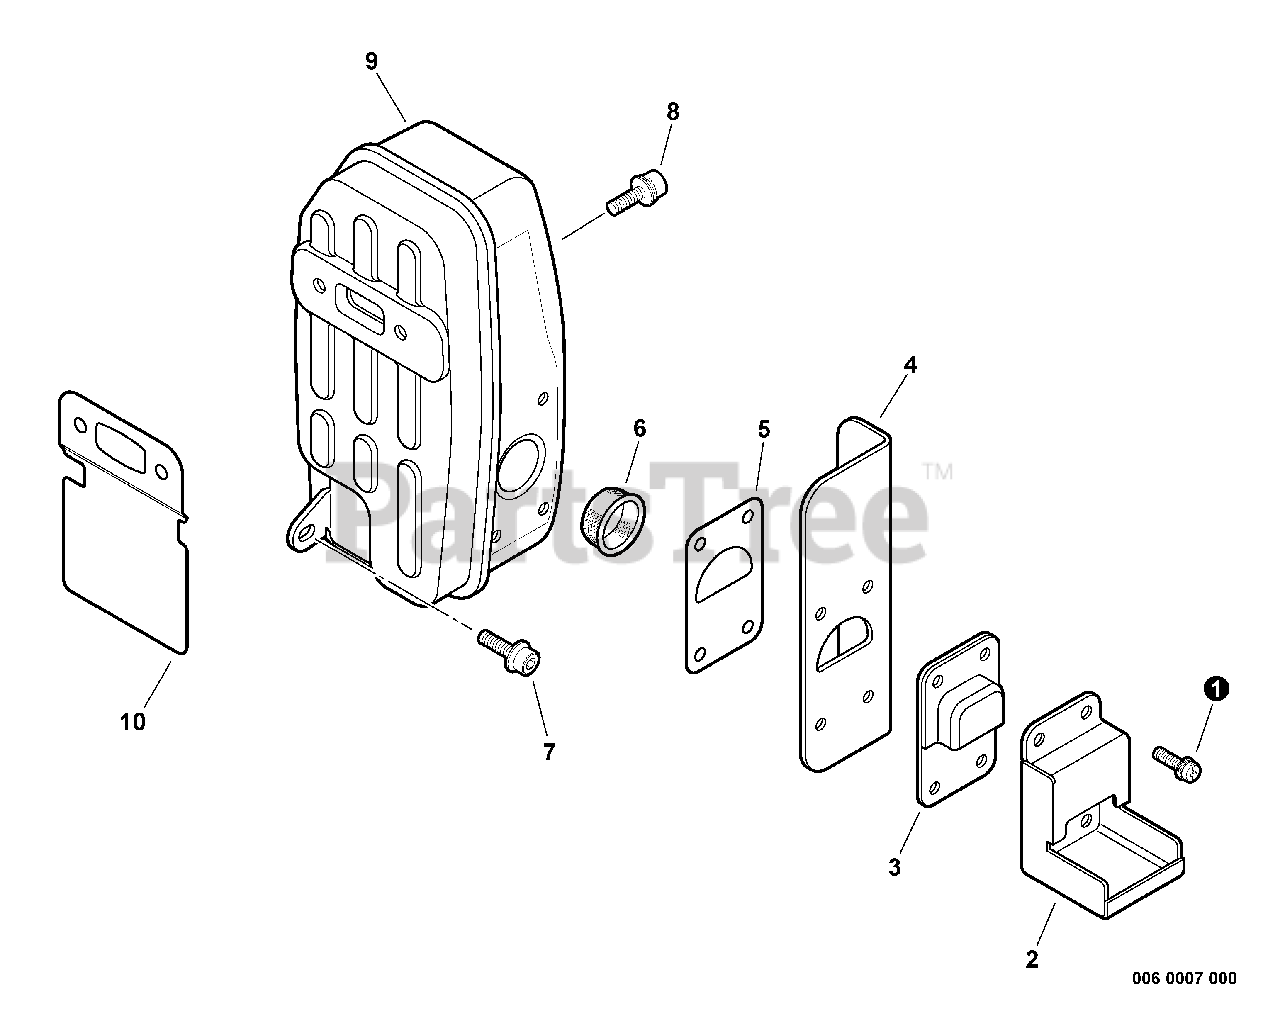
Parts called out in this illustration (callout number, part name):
1	SCREW 4×14
2	GUIDE, EXHAUST
3	GUIDE, EXHAUST
4	HEAT SHIELD, EXHAUST
5	GASKET, EXHAUST
6	SCREEN, SPARK ARRESTER
7	BOLT 5×14
8	BOLT, FLANGE 6×20
9	MUFFLER
10	SHIELD, EXHAUST
